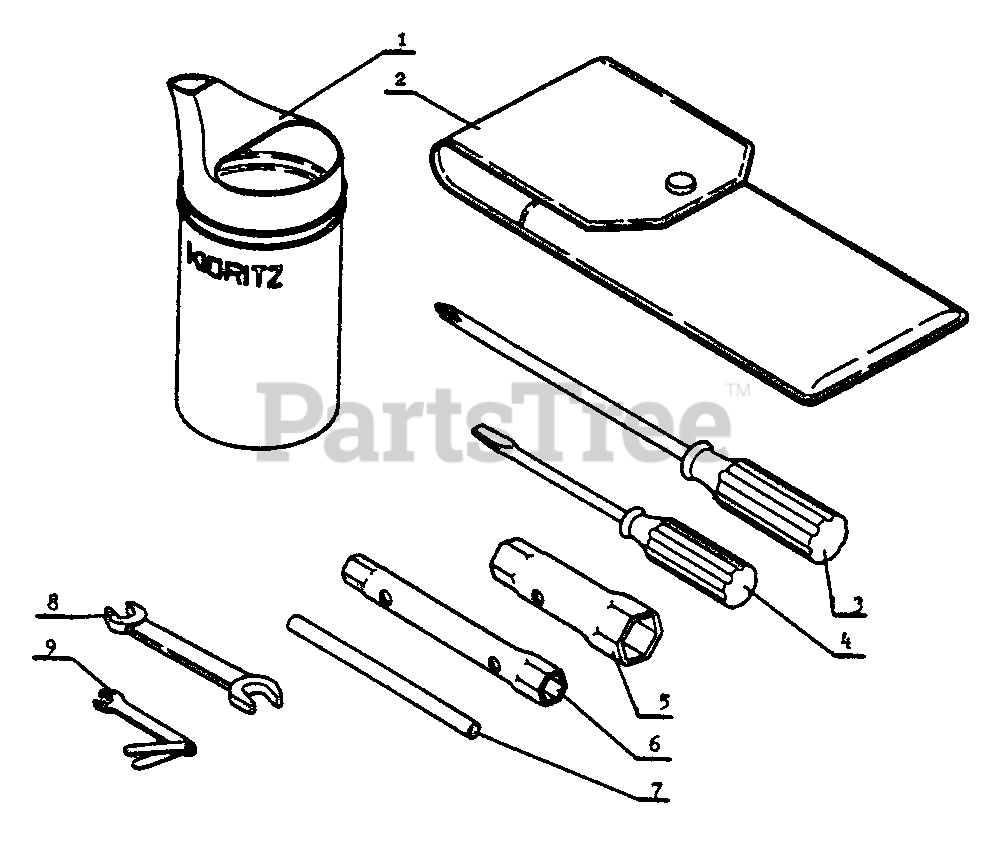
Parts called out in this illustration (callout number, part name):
1	FUEL MIXER
2	BAG, TOOL
3	SCREWDRIVER - CROSS HEAD
4	SCREWDRIVER - 50 MM
5	WRENCH 14×21
6	WRENCH 8×10
7	ROD, HANDLE
8	SPANNER 8×10
9	MAGNETO SPANNER
